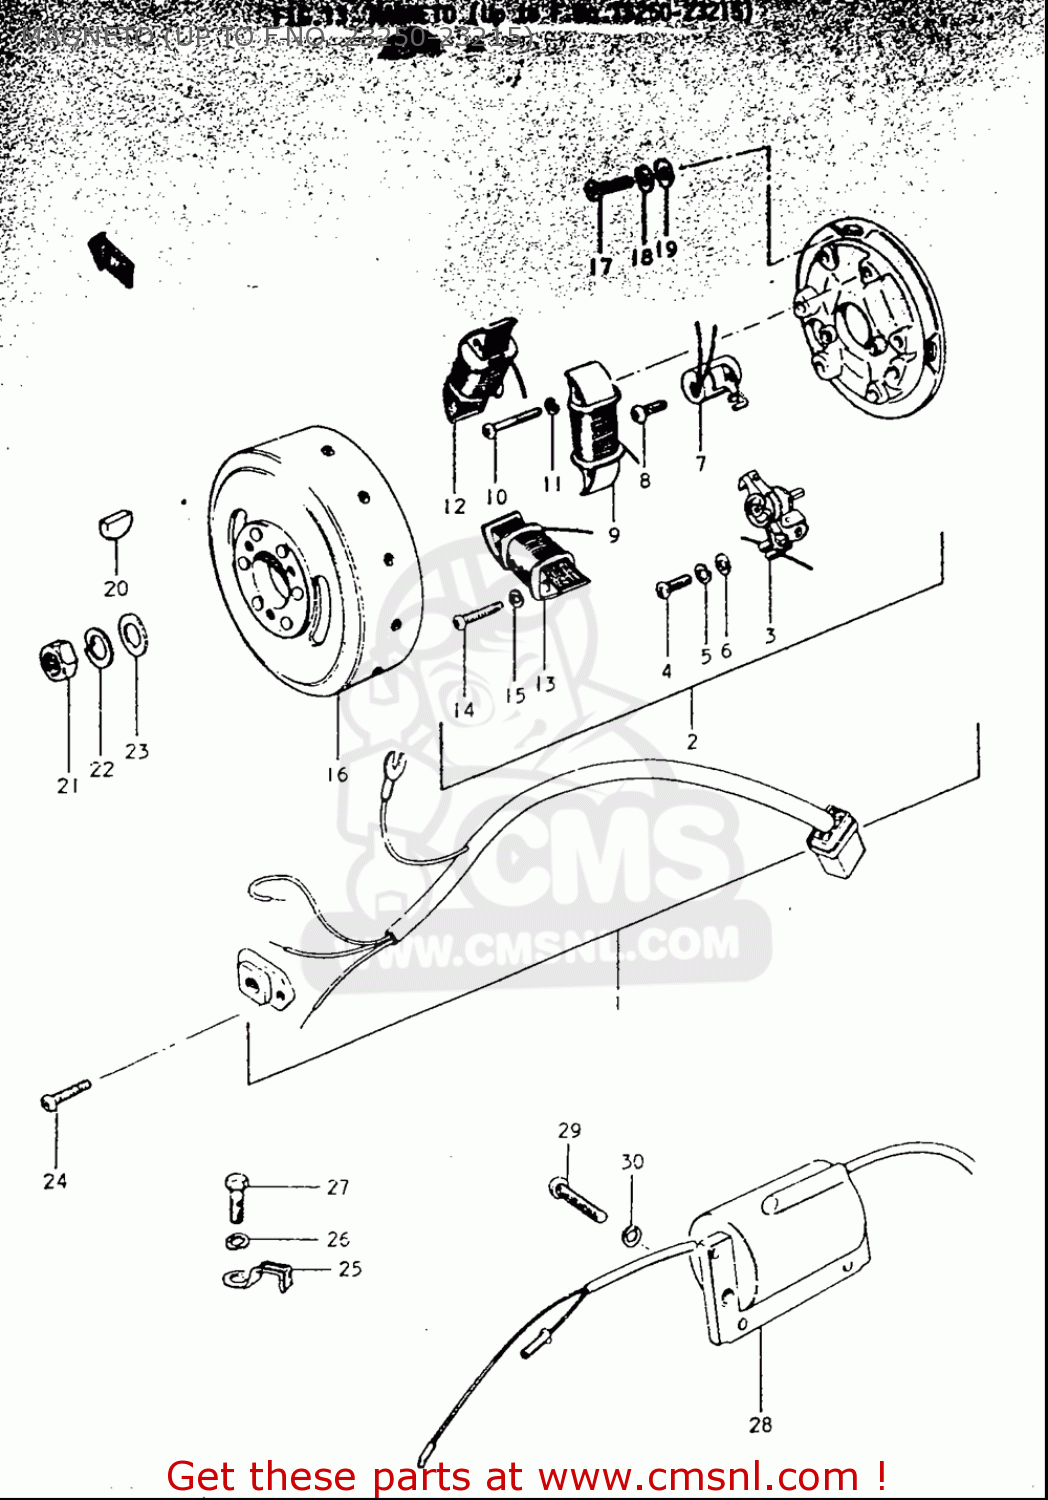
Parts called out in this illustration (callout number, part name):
3	POINT ASSY,CONTACT
4	.SCREW
5	WASHER,LOCK
6	WASHER
7	CONDENSER
8	SCREW
11	WASHER,LOCK
15	WASHER,LOCK
17	SCREW
18	WASHER,LOCK
19	WASHER
20	KEY
22	WASHER,LOCK
23	WASHER(12.5X24X2.3)
26	WASHER,LOCK
30	WASHER,LOCK
